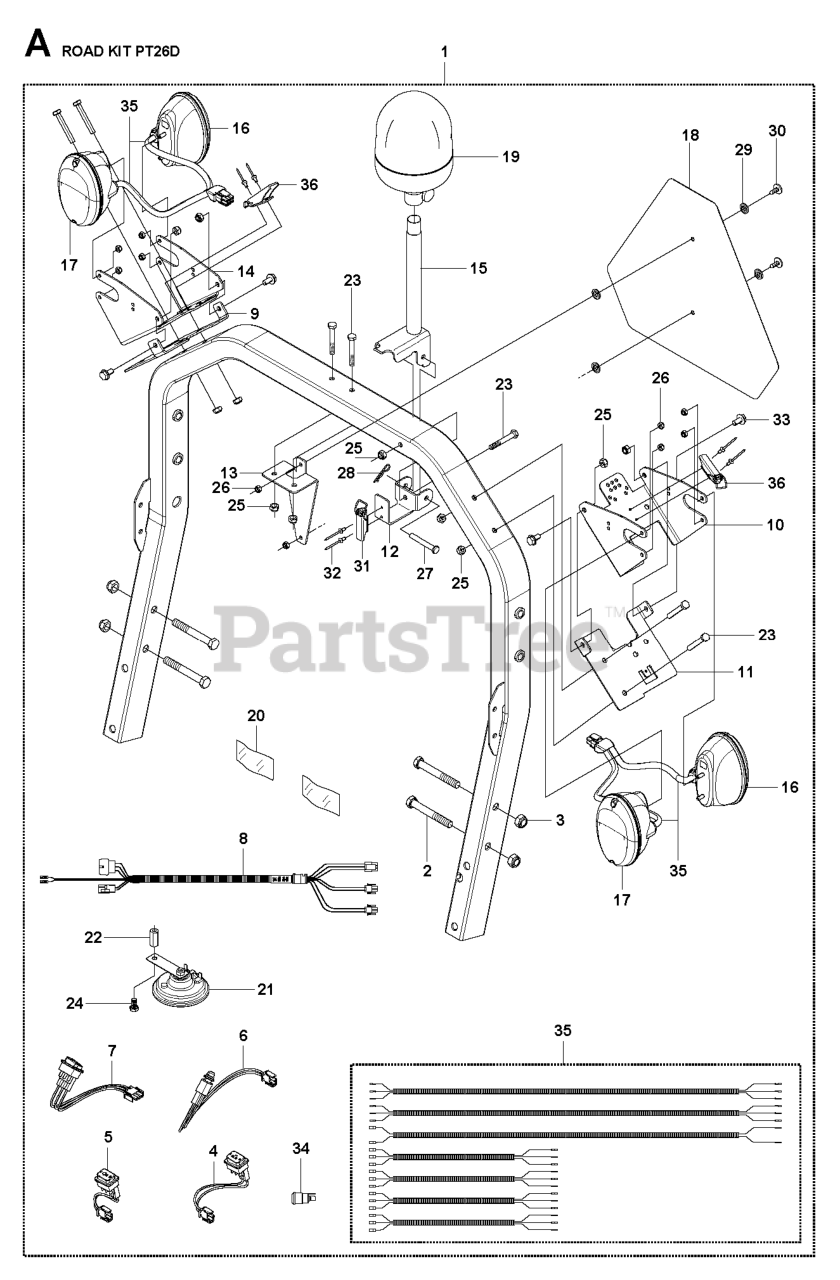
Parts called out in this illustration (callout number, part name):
24	BOLT - M8X16
25	LOCKNUT M8
26	LOCKNUT M6
28	SPRING COTTER
